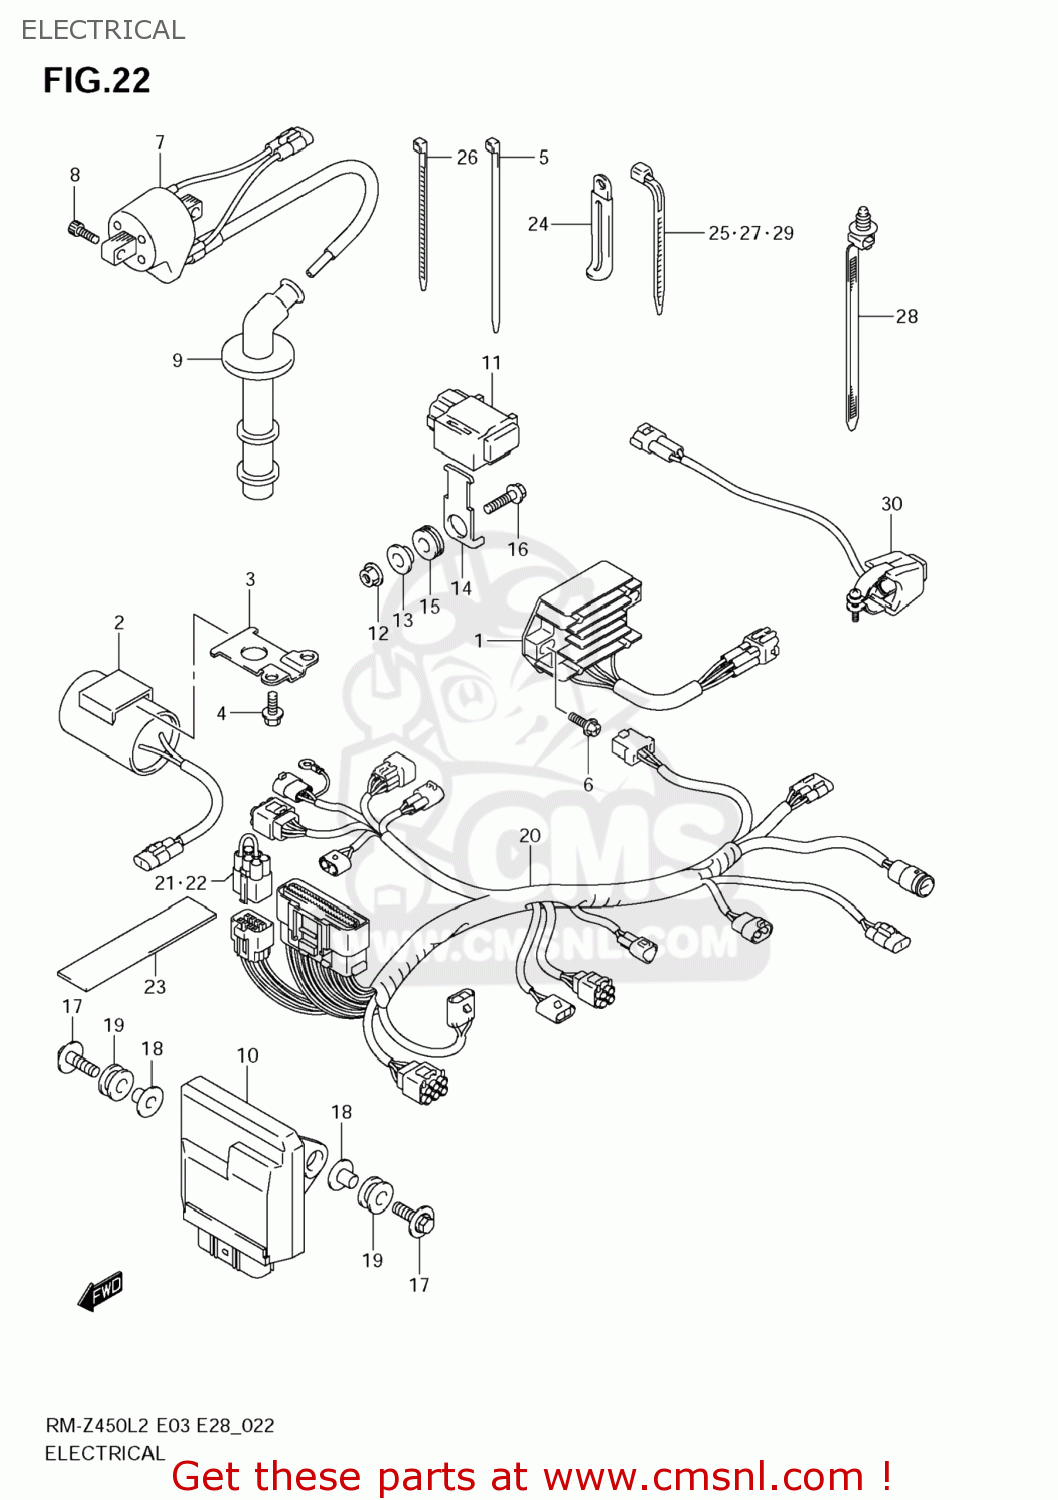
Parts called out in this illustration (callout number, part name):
1	RECTIFIER ASSY
2	CONDENSER ASSY
3	BRACKET,CONDENSER
4	BOLT(6X10)
5	CLAMP(L:100)
6	SCREW
7	COIL ASSY,IGNITION
8	BOLT
9	CAP ASSY,SPARK PLUG
10	CONTROL UNIT,FI
11	SENSOR ASSY,FUEL CUT
12	NUT
13	SPACER(6.2X8.4X10.9)
14	BRACKET,FUEL CUT SENSOR
15	CUSHION
16	BOLT
17	BOLT(6X20)
18	SPACER(6.2X8.4X10.9)
19	GROMMET
20	HARNESS,WIRING
21	WIRE,SHORT
22	WIRE,SHORT
23	COVER,HARNESS
24	CLAMP(L:45)
25	CLAMP(L:95)
26	CLAMP(L:95)
27	CLAMP(L:125)
28	CLAMP(L:154)
29	CLAMP(L:165)
30	SWITCH ASSY,ENGINE STOP
